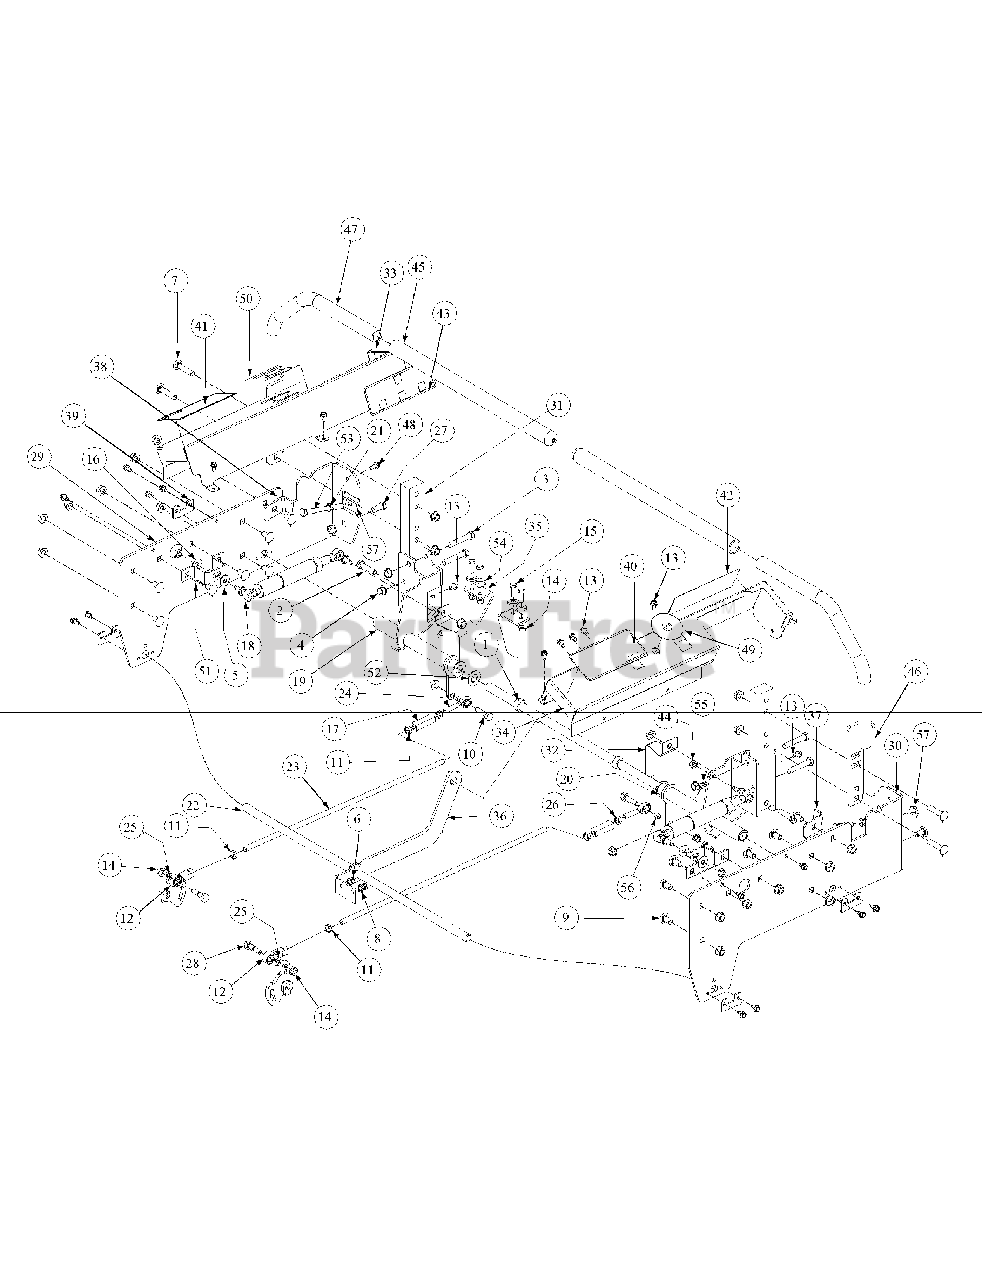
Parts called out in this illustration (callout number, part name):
1	Shaft Collar
2	HHCS, 3/8-16, 2.00
3	HHCS, 3/8-16, 2.25
4	Hex Nut, 3/8-16, Lock Flange
5	External Washer, 3/8
6	HHCS, 1/4-20, .750
7	Hex Carriage Screw, 3/8-16, 1.75
8	Lock Washer, 1/4 Zinc
9	Carriage Bolt, 3/8-16 x .75
10	Capscrew, 3/8-16 x 1-3/4
11	Hex Jam Nut, 3/8-24
12	B/Joint, 3/8-24, Right Hand Female
13	Screw, TT, 1/4-20, 0.5, Hex Index Washer
14	Nut, Lock, Hex Flange, 5/16-18
15	Hex, Cap Screw, 5/16-18 x 3/4
16	Belle Washer, .325 x .930 x .045
17	Turnbuckle
18	Cylinder Return to Neutral
19	Hub Assy, Control LH Bearing
20	Hub Assy, Control RH Bearing
21	Nut, 3/8-16, Jam
22	Shaft Control Brake Steering
23	Rod Connector 3/8 OD x 14.25
24	B/Joint, 3/8-24, Left Hand Female
25	5/16, Lock Washer
26	Nut, 3/8-24, Jam, LH Third
27	HHCS, 5/16-18 x 1.0
28	Screw, Shoulder Control Rod
29	Side Panel, Control, Left
30	Side Panel, Control, Right
31	Mounting Handle
32	Lever, Safety Switch
33	Control Panel, LH
34	Control Panel, RH
35	Switch Mounting Bracket, Lapbar
36	Link Mounting Control Shaft, Bracket
39	Holder Shaft, Park Brake
40	Decal , Right Hand Console
41	Decal, Left Hand Console
42	Decal Right Hand Control
43	Decal, Left Hand Control
44	Nut, Hex, Center Lock, M8
45	Grip, 1.0
46	Lapbar, Weldment, Right Handle
47	Lapbar, Weldment, Left Handle
48	Screw, TT, 1/4-20, 0.75, Hex Index Washer
49	Label, Ignition, 2.5 Diameter
50	Label, Control, Throttle and Choke
51	Bracket Assembly, Mount Dampener
52	Flat Washer, 5/8 Nylon
53	HHCS, 3/8-16, 3.00
54	Flat Washer, 5/16
55	Grease Fitting, 90 degree
56	Spacer, .385ID x .625 OD x >50 Lg
57	U-Nut, 3/8-16, .75
